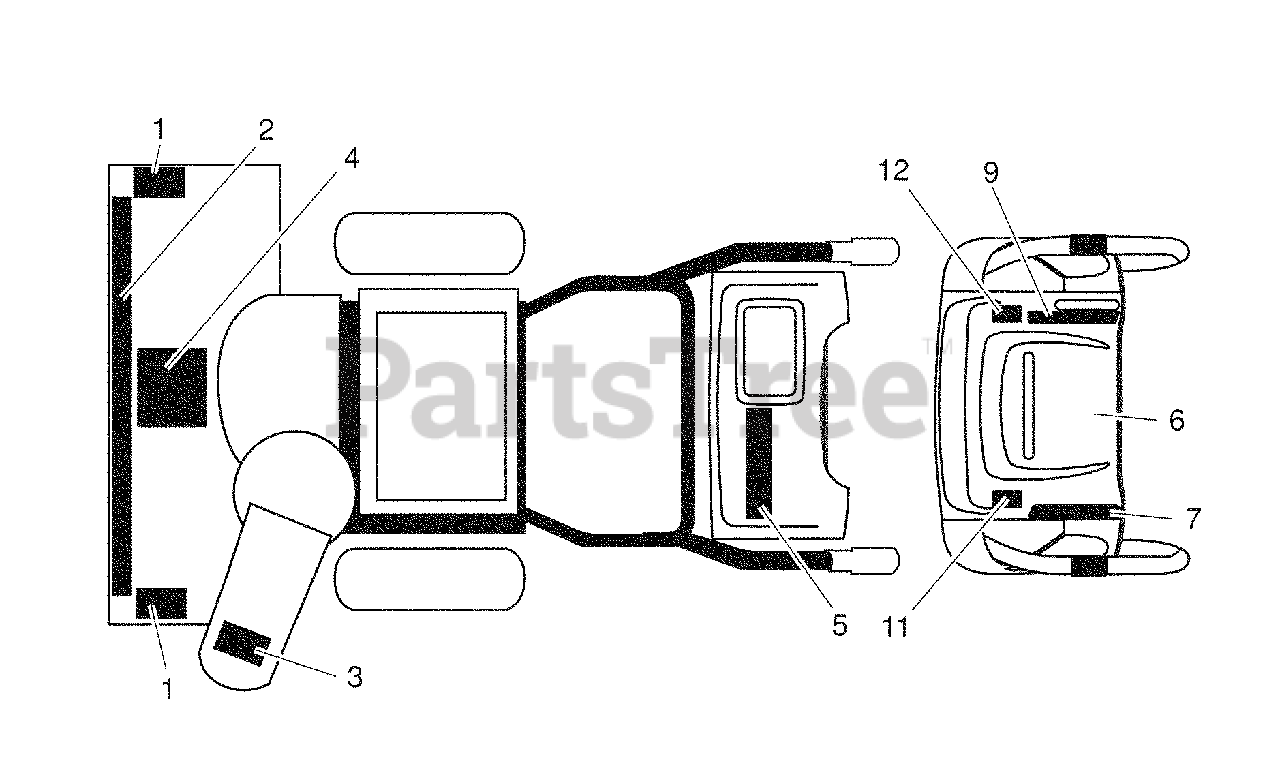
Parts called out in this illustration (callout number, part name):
1	DECAL, DANGER
2	DECAL, HUSQVARNA 1330SB-XLSB
3	DECAL, DANGER, DEFLECTOR
4	DECAL, DANGER
5	DECAL, HUSQVARNA 1330SB-XLSB
6	DECAL, INSTRUCTION
7	DECAL, REMOTE DEFLECTOR
9	DECAL, SPEED CONTROL
11	DECAL, LH TRIGGER
12	DECAL, RH TRIGGER
